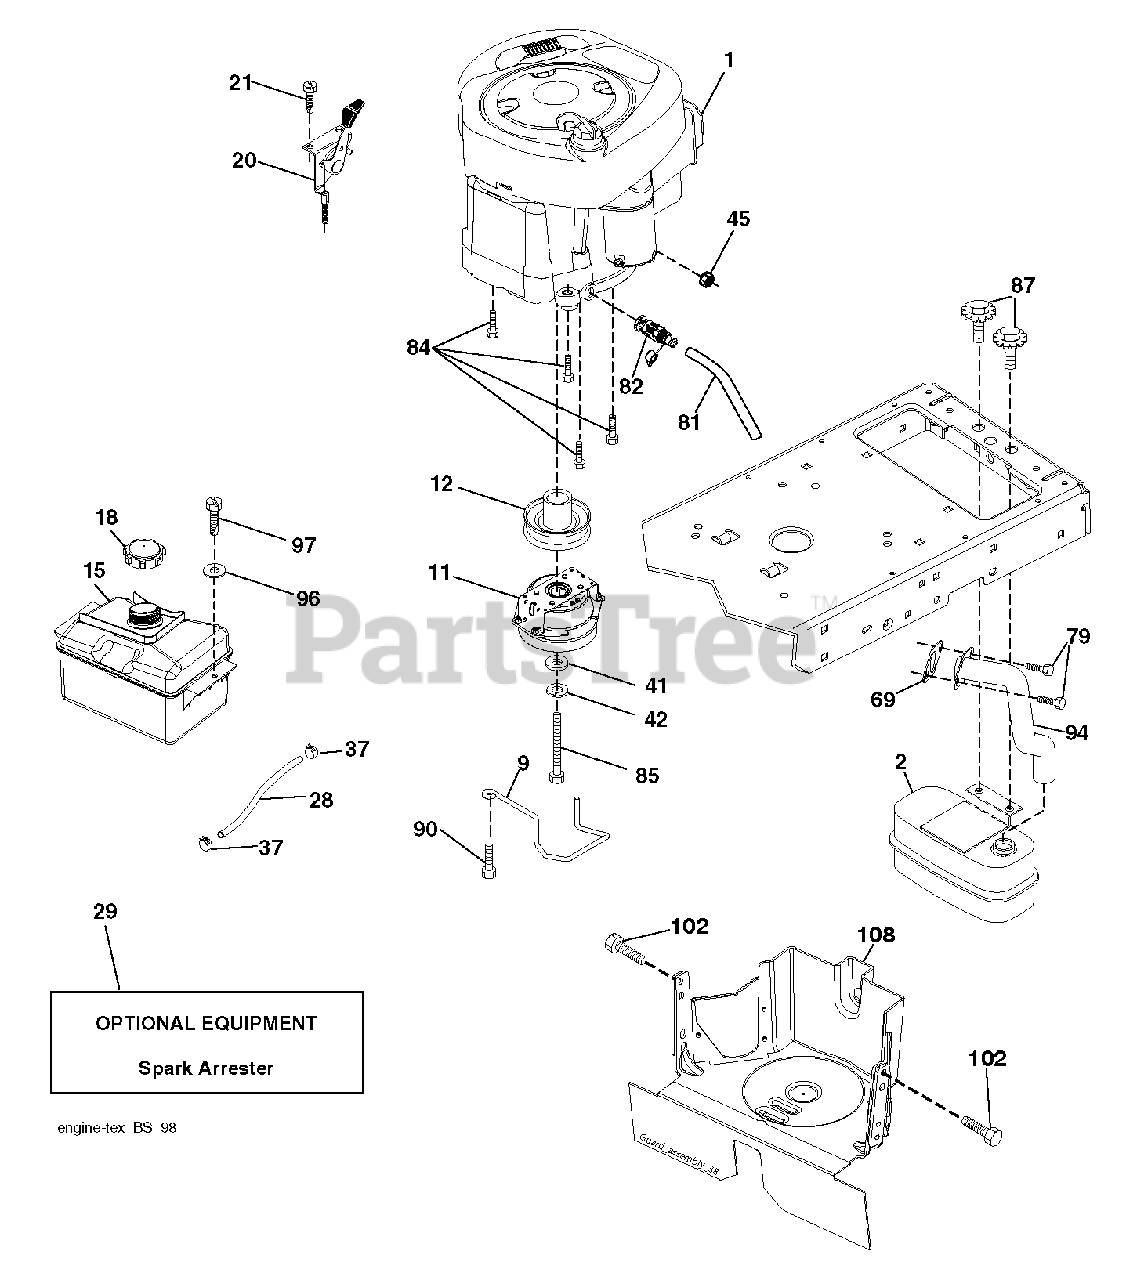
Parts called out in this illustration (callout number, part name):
2	MUFFLER.SINGLE.LRG.BRIGGS.KOHL
9	KEEPER BELT ENGINE
11	CLUTCH.OGURA.5.0PD.GT1.5A-EH07
12	PULLEY.ENGINE.TUFFTORQ
15	FUEL.TANK.ASM.NON-EPA
18	CAP ASM.FUEL.2.25"FR.
20	THROTTLE.COBRA.21".RSTART.BLK
21	SCREW.#10 X 0.750.BOS
28	LINE.FUEL.20
29	KIT.SPARK ARRESTOR 794945 B&S
37	HOSE CLAMP
42	LOCKWASHER
45	NUT
69	REPL BY 532 27 22-93
79	SCREW.SOCKET HD.5/16-1
81	TUBE, DRAIN OIL ASM.
82	VALUE.OIL.DRAIN
84	SCREW.3/8-16
85	BOLT HEX 7/16-20 X 3.75 GR. 5
87	BOLT, 5/16-18 X 1 3/4
90	SCREW 3/8-16X1
94	EXHAUST.TUBE.B&S.28/31
97	SCREW HEXWSHR 1/4-20X3/4
102	SCREW 5/16-18X1
108	COVER PULLEY
